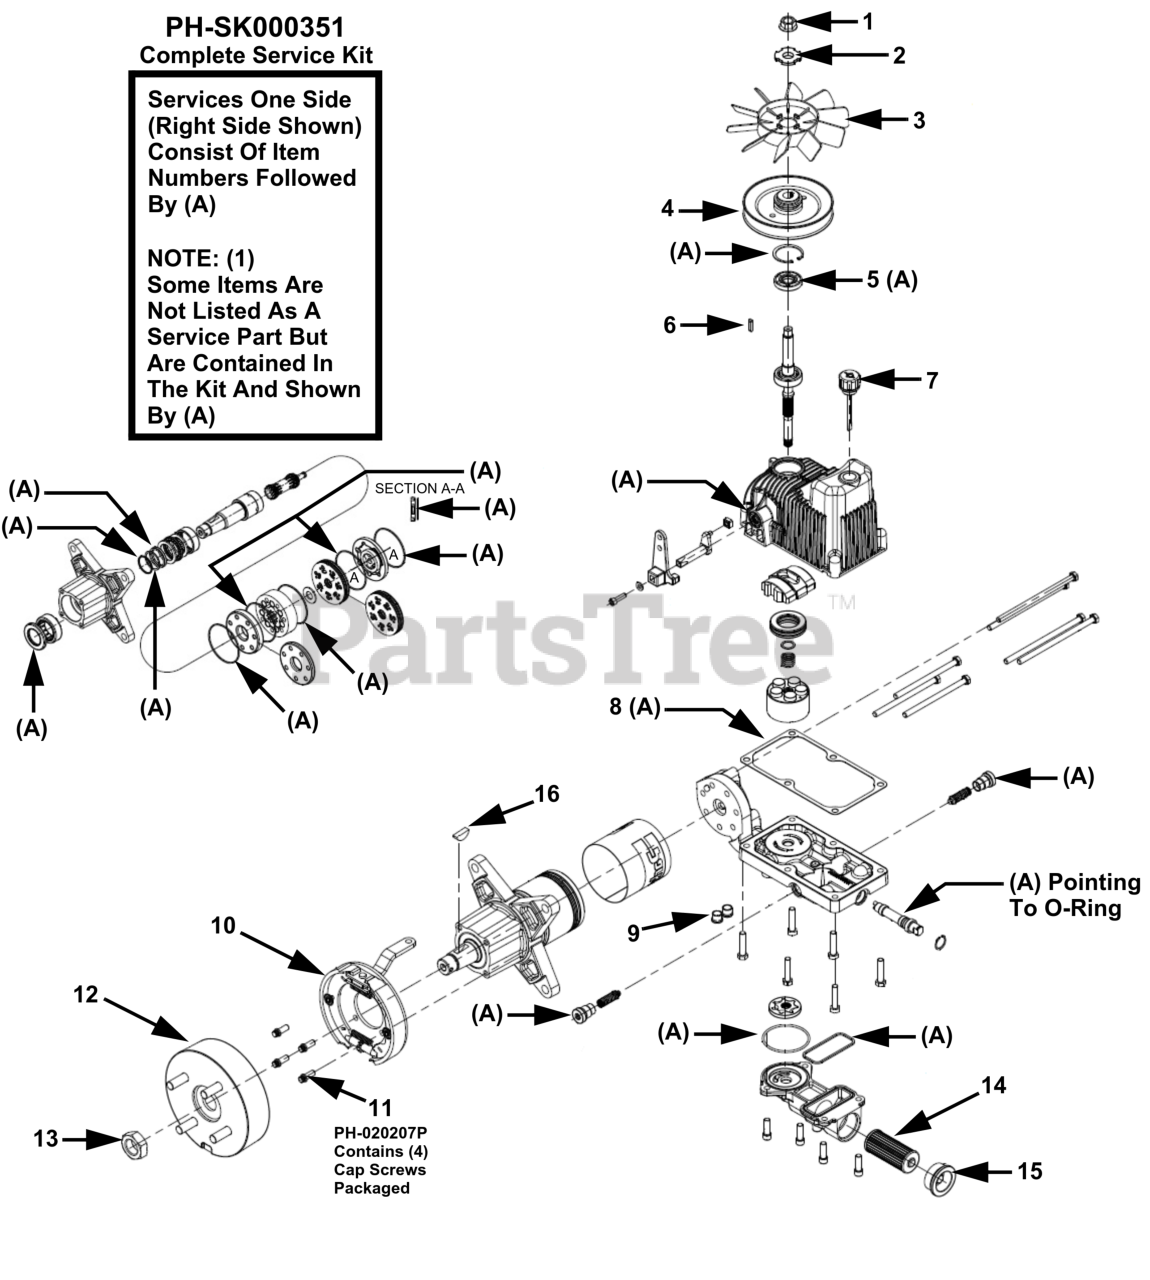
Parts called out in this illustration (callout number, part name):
1	NUT-FLANGE 1/2-20
2	SPACER-FAN
6	SQUARE SHOULDER KEY WAY
7	BREATHER
9	PLUG-MAGNETIC HEX
10	BRAKE ASSEMBLY-ON HOLE LEVER
11	SCREW-CAP (QTY 4)
12	DRUM-4 BOLT BRAKE
13	NUT-SLOTTED
15	PLUG & O-RING ASSE
16	WOODRUFF KEY
17	ROTATING BRACKET
A	COMPLETE SEAL SERVICE KIT
